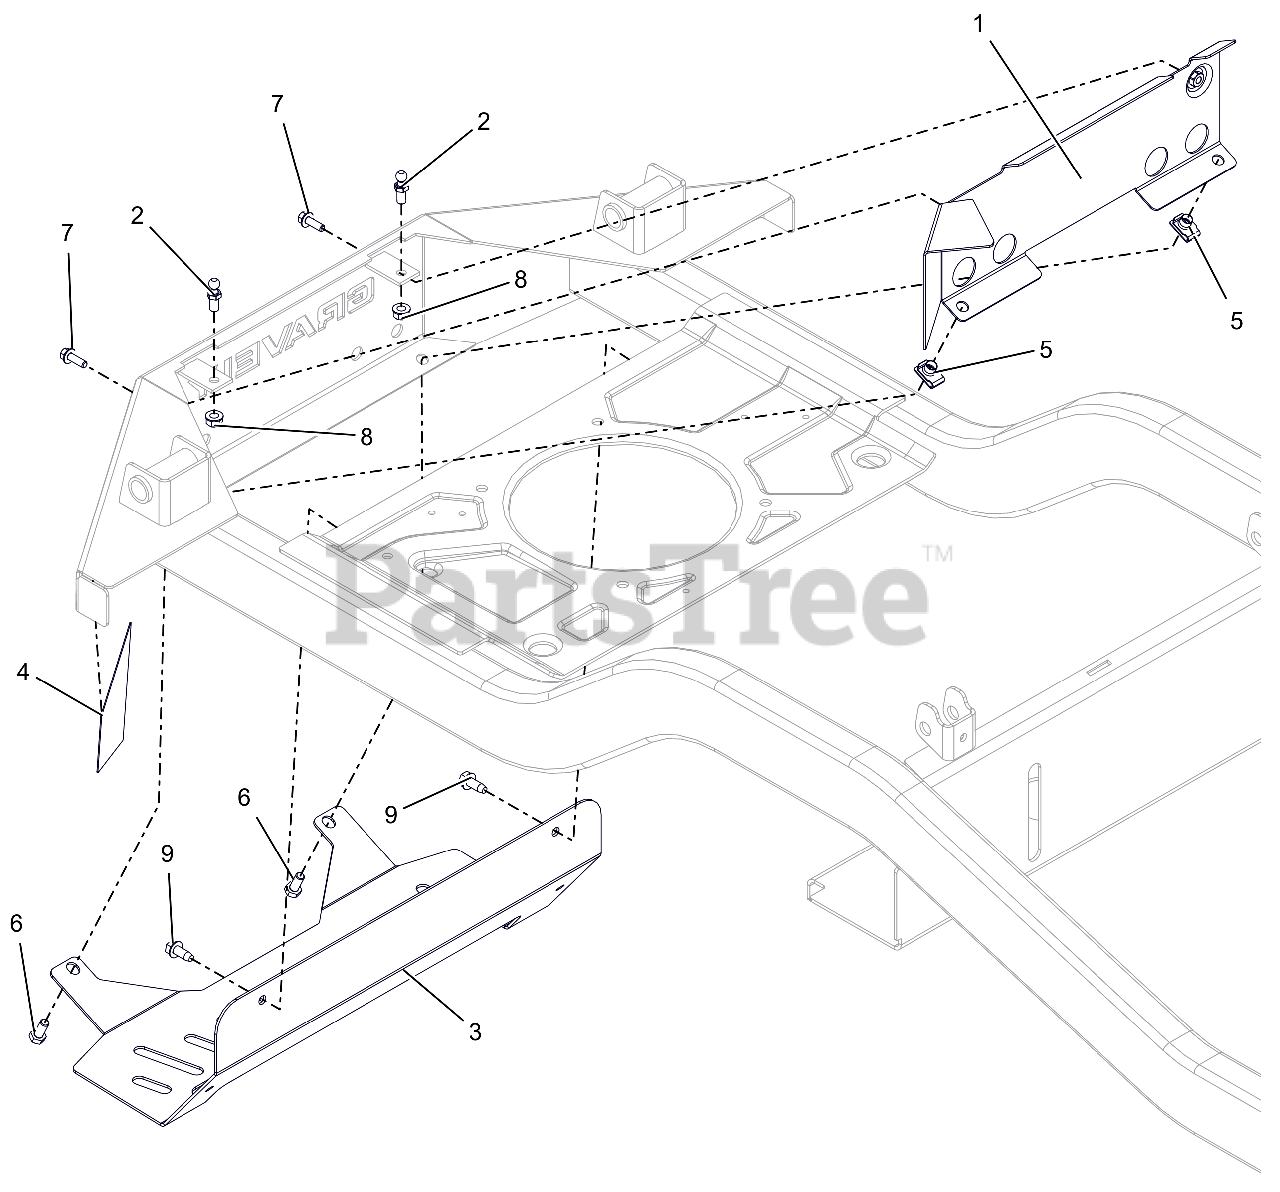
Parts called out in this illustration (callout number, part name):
1	WMT, HEAT BAFFLE
2	STUD- BALL
3	SHIELD, HEAT (HD)
4	TAPE, HEAT DEFLECTOR
5	NUT-CLIP RETAINER 5/16-18X.56
6	BLT,HEX .31-18X.75 G5 ZCC
7	BLT,HEX-FLG .25-20X.75 G5 BFP
8	NUT,LK-CTR-FLG .31-18 GF ZCC
9	SCR,TAP .312-18X.75 HWH TR ZCC
